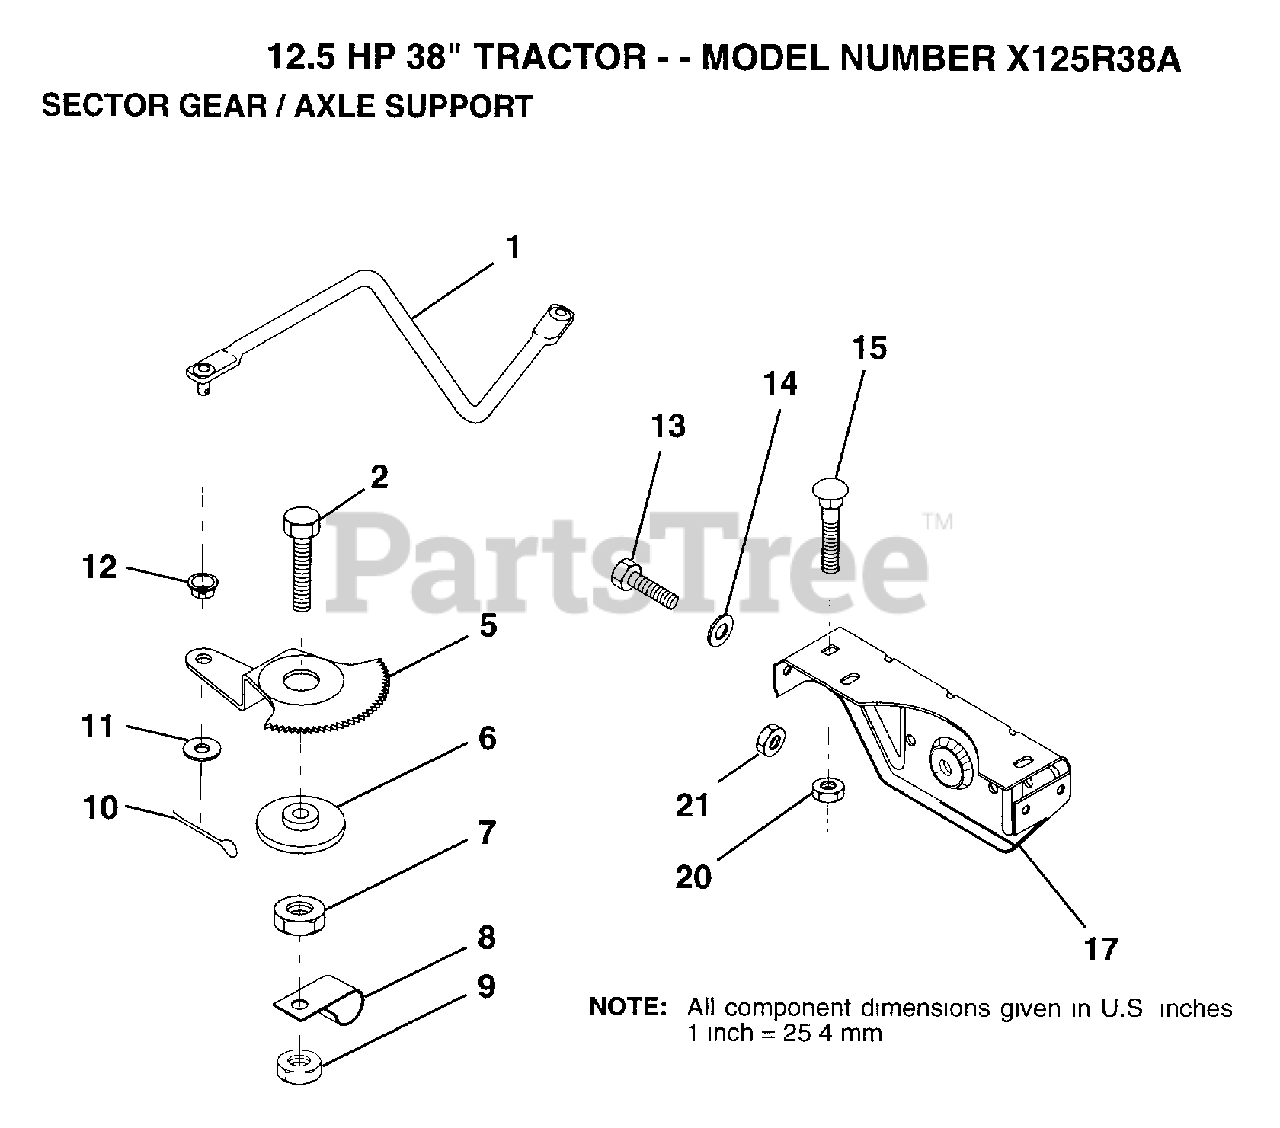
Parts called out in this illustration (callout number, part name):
1	DRAG LINK
2	"BOLT,HEX"
5	GEAR SECTOR
6	BUSHING
7	NUT
8	CLIP INSULATOR
9	NUT LTV
10	COTTER PIN
11	WASHER
12	BUSHING.DRAGLINK
13	BOLT
14	WASHER
15	BOLT
17	SUPT AXLE FRONT
